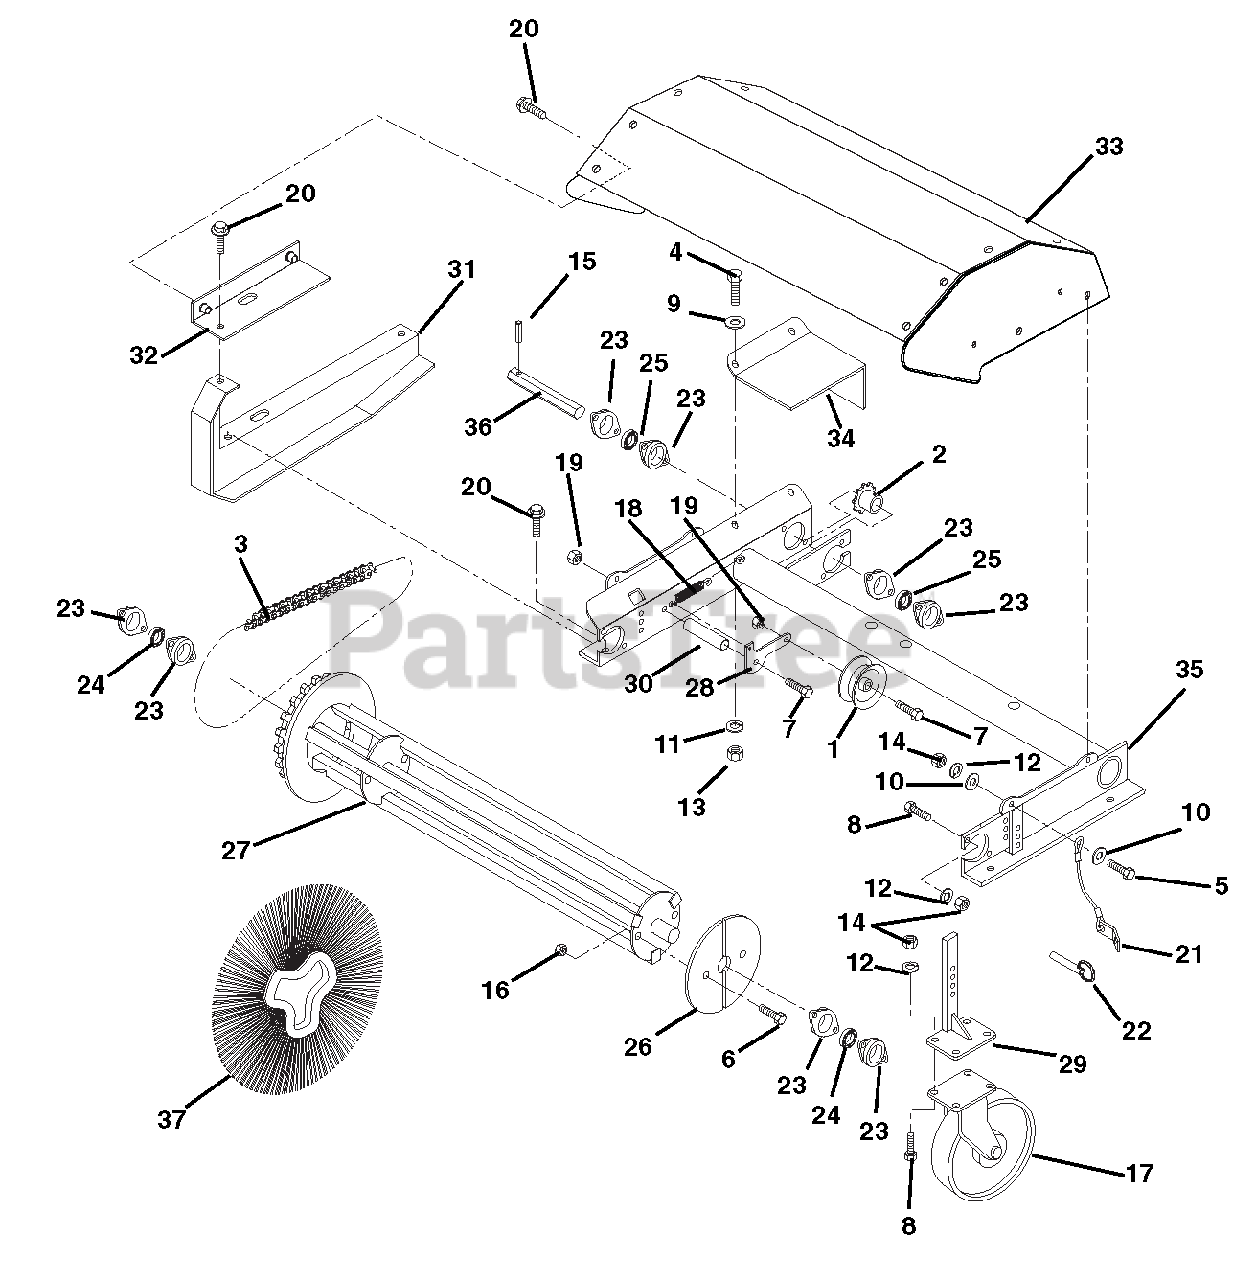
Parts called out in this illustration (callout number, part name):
1	CHAIN TIGHTENER
2	SPROCKET
3	CHAIN, ASS'Y #40X106 EDLS W/LK
4	@BLT-HEX .25-20X.75 GR5 YWZC
5	@BLT-HEX .31-18X1.00 GR5 YWZC
6	@BLT-HEX .31-18X2.25 GR5 YWZC
7	@BLT-HEX .38-16X1.50 GR5 YWZC
8	@BLT-HEX .31-18X.75 GR5 YWZC
9	@WSHR-FL-STL.281X.62X.065 YWZC
10	@WSHR-FL-STL.312X.734X.065 YWZ
11	@WSHR-LK .25X.062 REG YWZC
12	@WSHR-LK .31X.078 REG YWZC
13	@NUT-HEX .25-20 YWZC
14	@NUT-HEX .31-18 YWZC
15	PIN, SPRING LOK .187 X 1.25
16	NUT, LOK STAMPED .312-18 TINN.
17	WHL, 5 DIA.
18	SPRING, TENSION .50 X 3.0
19	@NUT-LK-CTR .38-16 YWZC
20	SCREW, GR 10.9 M6X1-20
21	LANYARD,.06 CAB.1.25X6,TYP C
22	PIN,SPRING BALL .375 X 1.00
23	FLANGE, SPHERICAL 2"
24	BRG 1.00 BORE, SPHER. OD.
25	BRG-BALL .884HEXX52MMX1.07
26	RETAINER PLATE (SET OF 2)
27	WELD, CORE C36TW
28	ARM, IDLER,BRM C36TW
29	WELD, CASTER LEG, C36TW
30	BSHG, .62X12 GA X.75
31	SHIELD,CHAIN, ARIENS
32	SHIELD, CHAIN,TOP,ARIENS
33	KIT, HD, ARIENS
34	SHIELD, INPUT, ARIENS
35	WELD, BFRM,ARIENS
36	SHAFT, HEX 20.1", W/HOLE
37	SET,SECTION,24",P,CONV.
